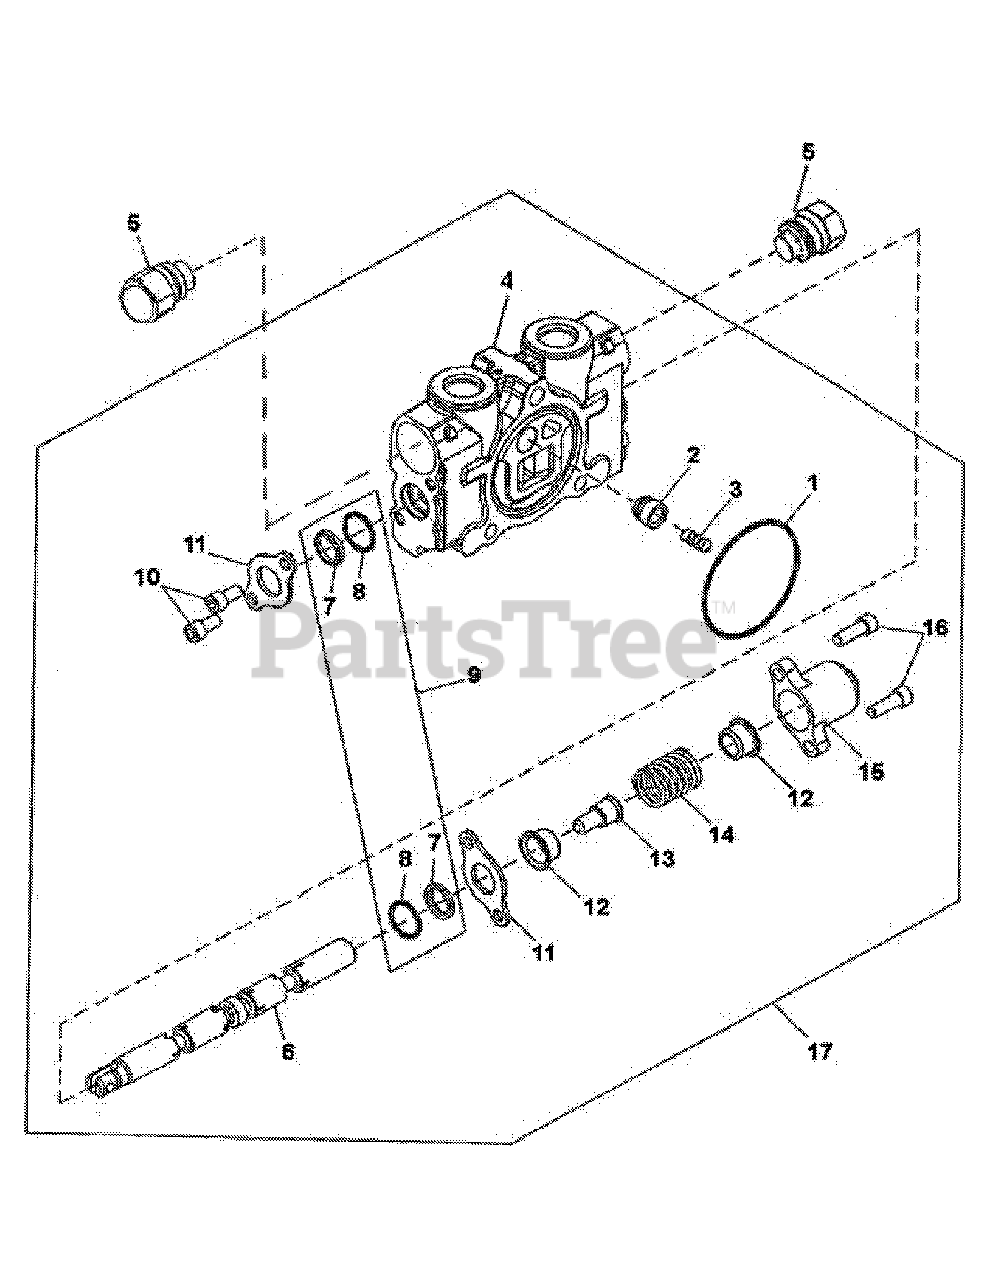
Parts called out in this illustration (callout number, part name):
1	O-Ring
2	Poppet, Load Check
3	Spring, Load Check
4	Valve Section
5	Plug, Shut Off
7	Wiper, Spool
8	O-Ring, Spool
9	Seal Kit, Minor (contains two of Item 7 & 8)
10	Cap Screws, Socket Head
11	Plate, Retainer
12	Seat, Spring
13	Screw, Spring Seat
14	Spring, Spool Centering
15	Cap, Spring Spool
16	Cap Screws, Socket Head
17	Valve Section Assembly (less Item 5)
18	Seal Kit, Major
19	Load Check Poppet Kit
20	Spring Centered Spool Positioner Kit
